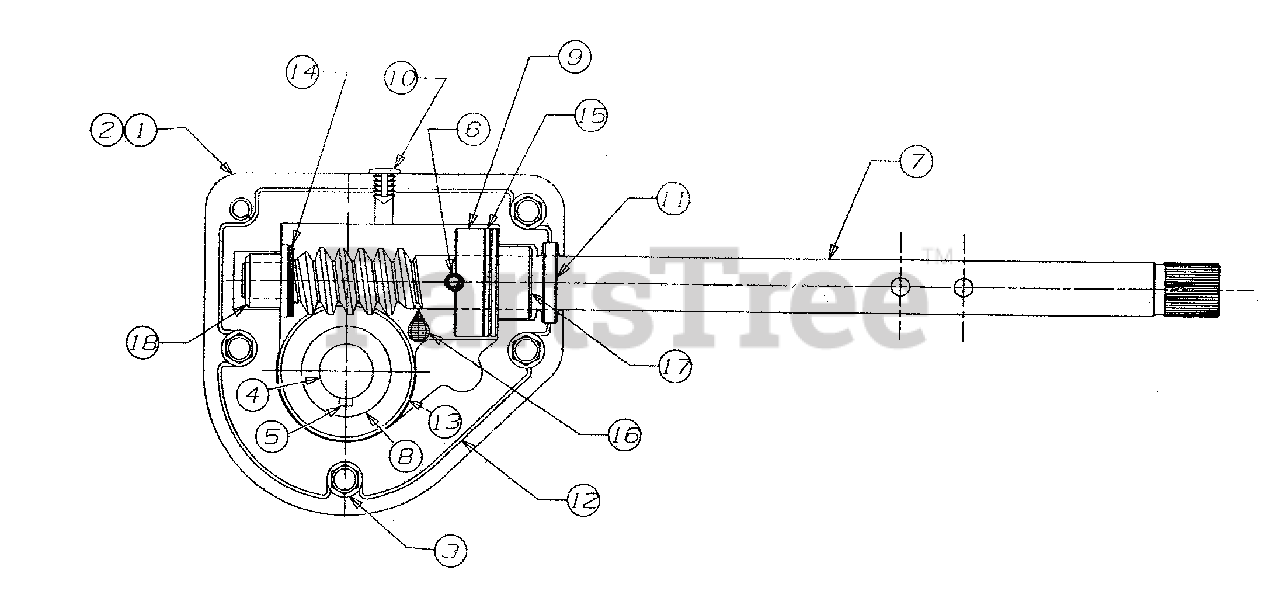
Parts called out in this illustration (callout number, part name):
1	Housing - L.H.
2	Housing - R.H.
3	Screw
4	Spiral Axle 26"
5	Key
6	Pin - Spiral
7	Shaft - Worm
8	Gear - Worm
9	Collar - Thrust
11	Seal - Oil
12	Locktite 5699
13	Washer - Flat
14	Washer - Flat
15	Washer - Flat
16	Grease
17	Bearing - Flange
18	Bearing - Flange
